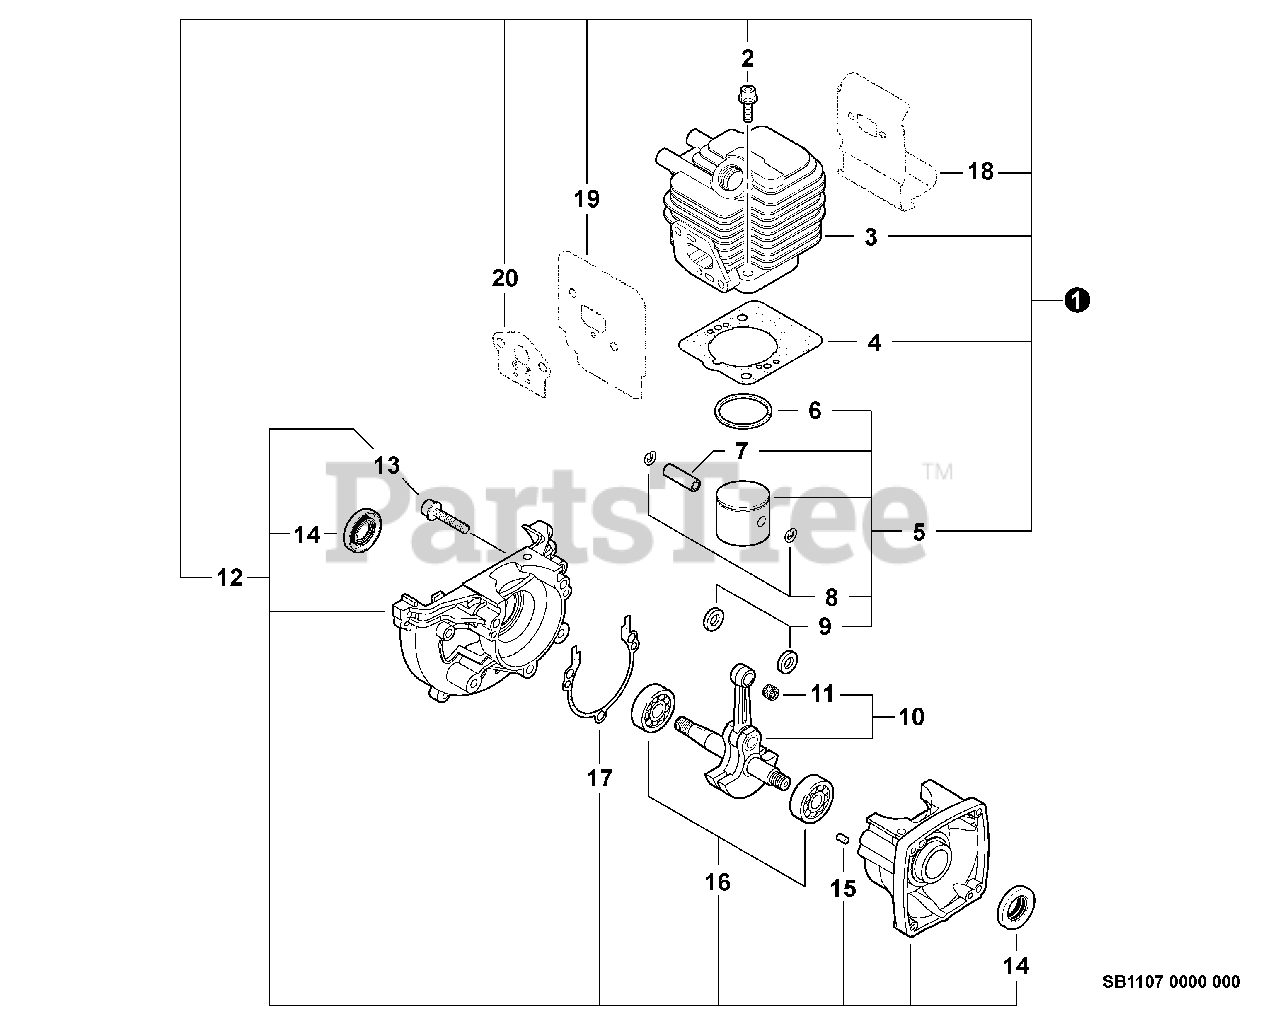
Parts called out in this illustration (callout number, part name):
1	SHORT BLOCK -- SB1107
2	SCREW - 5X22
3	CYLINDER
4	GASKET, CYLINDER
5	PISTON KIT
6	RING, PISTON
7	PIN, PISTON
8	RING, RETAINING
9	SPACER, PISTON
10	CRANKSHAFT ASSY
11	BEARING, NEEDLE - 8
12	CRANKCASE KIT
13	SCREW - 5X28
14	SEAL, OIL
15	PIN - LOCATING
16	BEARING, BALL - 6201
17	GASKET, CRANKCASE
18	SHIELD, EXHAUST
19	SHIELD, INTAKE
20	GASKET, INTAKE
